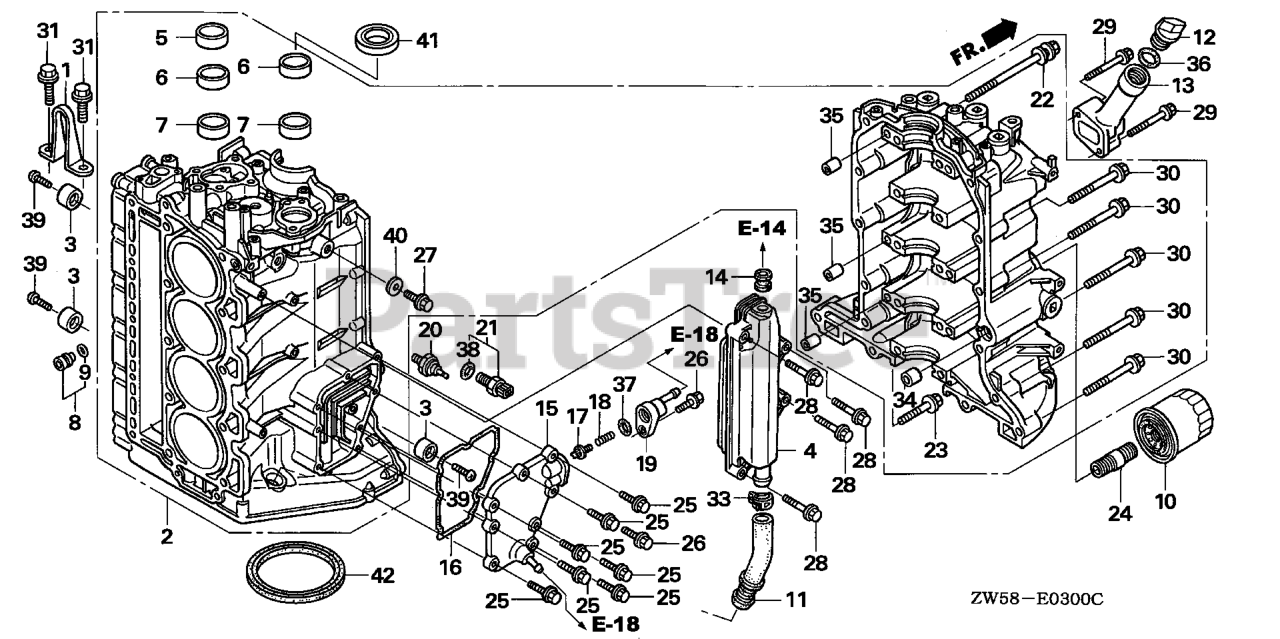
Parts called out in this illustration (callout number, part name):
1	HANGER, ENGINE
2	BLOCK ASSY., CYLINDER *NH8* (DARK GRAY)
3	METAL, ANODE
4	CHAMBER, PCV
5	METAL, BALANCER SHAFT (NO.1) (DAIDO)
6	METAL, BALANCER SHAFT (NO.2) (DAIDO)
7	METAL, BALANCER SHAFT (NO.3) (DAIDO)
8	ORIFICE ASSY., OIL CONTROL
9	O-RING (10.8X2.4) (ARAI)
10	FILTER, OIL
10	FILTER, OIL (Honda Code 6836290). (SOLD INDIVIDUALLY)
11	TUBE SET, OIL
12	CAP, OIL
13	EXTENSION, OIL FILLER
14	GROMMET, PCV VALVE
15	COVER, OIL WATER JACKET *NH8* (DARK GRAY)
16	GASKET, OIL WATER JACKET COVER
17	VALVE, OIL WATER JACKET PRESSURE
18	SPRING, OIL WATER JACKET PRESSURE VALVE
19	HOLDER, OIL WATER JACKET PRESSURE VALVE
20	SWITCH ASSY., OIL PRESSURE
21	SENSOR ASSY., WATER TEMPERATURE
22	BOLT-WASHER (11X131)
23	BOLT, FLANGE (10X40)
24	HOLDER, OIL FILTER
25	BOLT, FLANGE (6X20)
26	BOLT, FLANGE (6X25)
27	BOLT, DRAIN PLUG (12MM)
28	BOLT, FLANGE (6X35)
29	BOLT, FLANGE (6X40)
30	BOLT, FLANGE (10X55)
31	BOLT, FLANGE (12X30)
33	CLAMP, TUBE (D29)
34	PIN, DOWEL (18X22)
35	PIN, DOWEL (13X20)
36	O-RING (26X2.7)
37	O-RING (16.5X2.5)
38	O-RING (9.5X1.5) (HONDA KIKAKI)
39	SCREW, PAN (6X18)
40	WASHER, DRAIN PLUG (12MM)
41	OIL SEAL (40X52X7)
42	OIL SEAL (98X80X10) (NOK)
